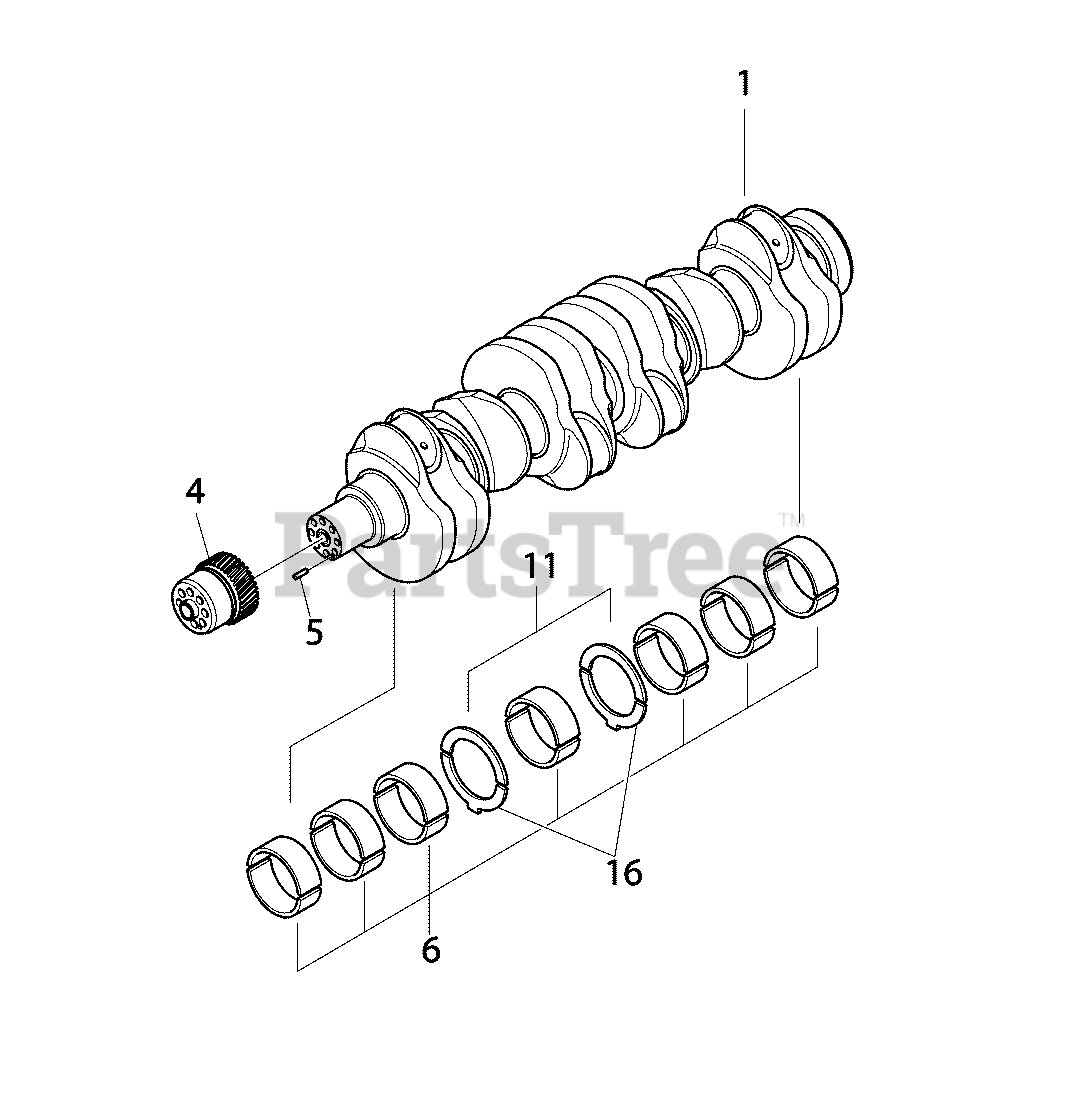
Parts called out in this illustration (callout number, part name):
1	* CRANKSHAFT
3	* BEARING, MAIN (.75 )
4	* GEAR, CRANKSHAFT
5	* PIN, DOWELL
6	* BEARING, MAIN (STD)
7	* BEARING, MAIN (.25)
8	* BEARING, MAIN (.50)
10	* BEARIN,MAIN (1.00)
11	* BEARING THRUST (UPPER STD)
12	* BEARING, THRUST (UPPER .25)
13	* BEARING, THRUST (UPPER .50)
14	* BEARING, THRUST (UPPER .75)
15	* BEARING, THRUST (UPPER 1.0)
16	* WASHER, THRUST (LOWER STD)
17	* WASHER, THRUST (LOWER .25)
18	* WASHER, THRUST (LOWER .50)
19	* WASHER, THRUST (LOWER .75)
20	* WASHER, THRUST (LOWER 1.0)
